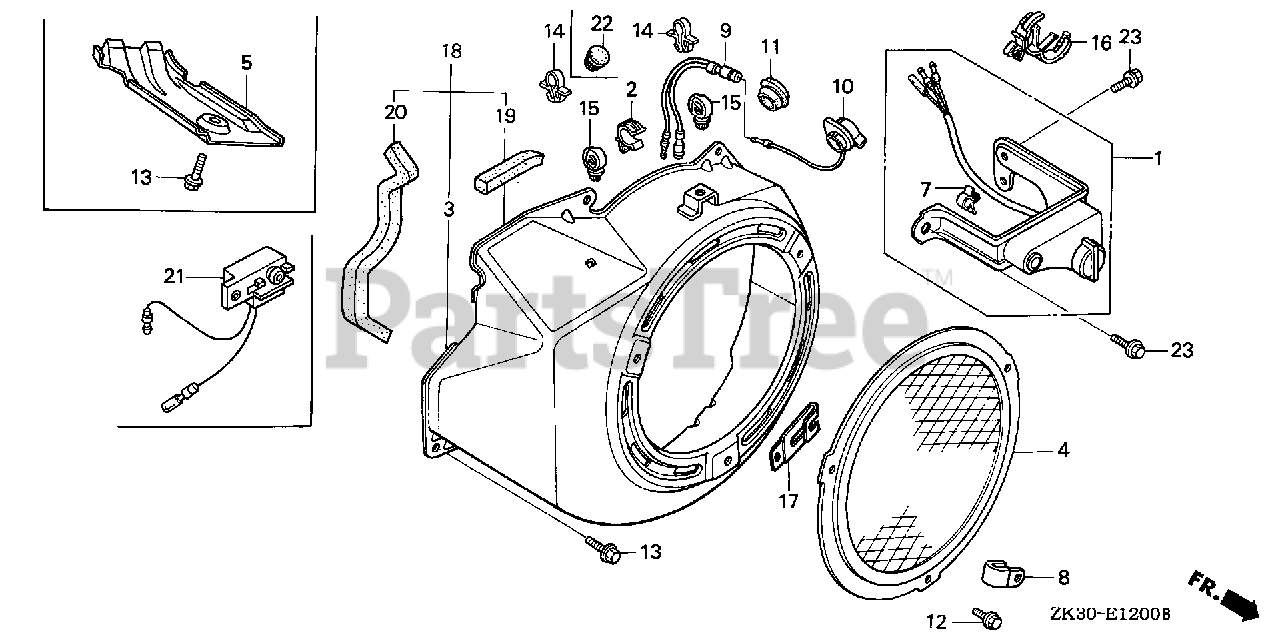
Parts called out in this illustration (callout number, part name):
3	COVER, FAN *NH1* (BLACK)
9	SUB-HARNESS
11	GROMMET, DRAIN HOLE
13	BOLT, FLANGE (6X12) (CT200)
14	CLIP, WIRE HARNESS (6MM) (WHITE)
16	CLIP, HARNESS
